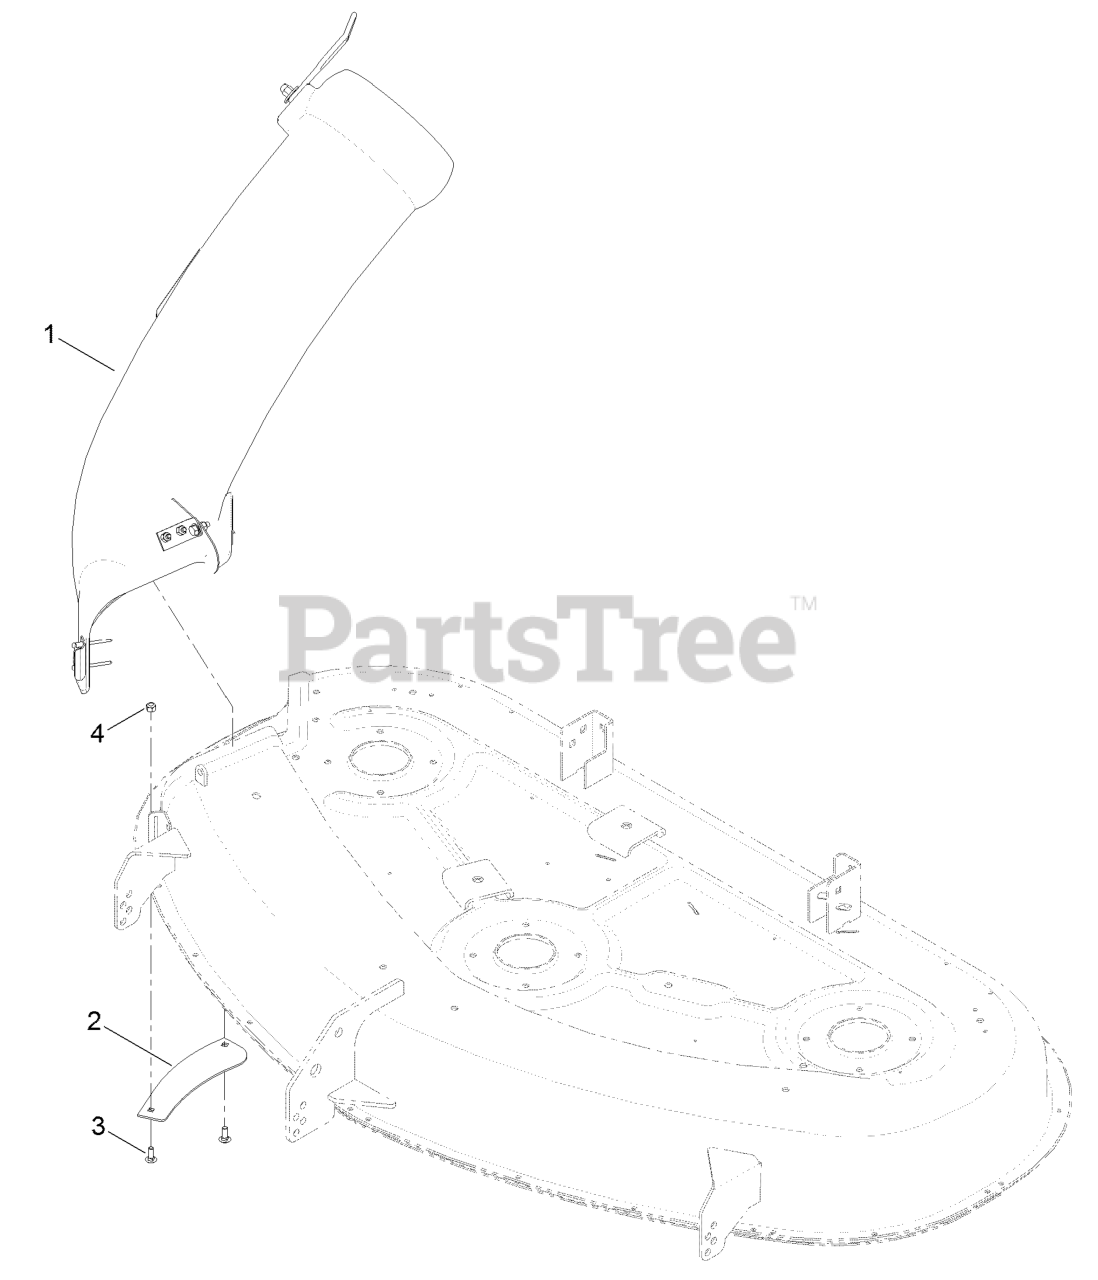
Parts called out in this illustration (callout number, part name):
1	50 INCH CHUTE ASM
2	BAFFLE-BLOWOUT
3	BOLT-CARR
4	NUT-LOCK, NI
